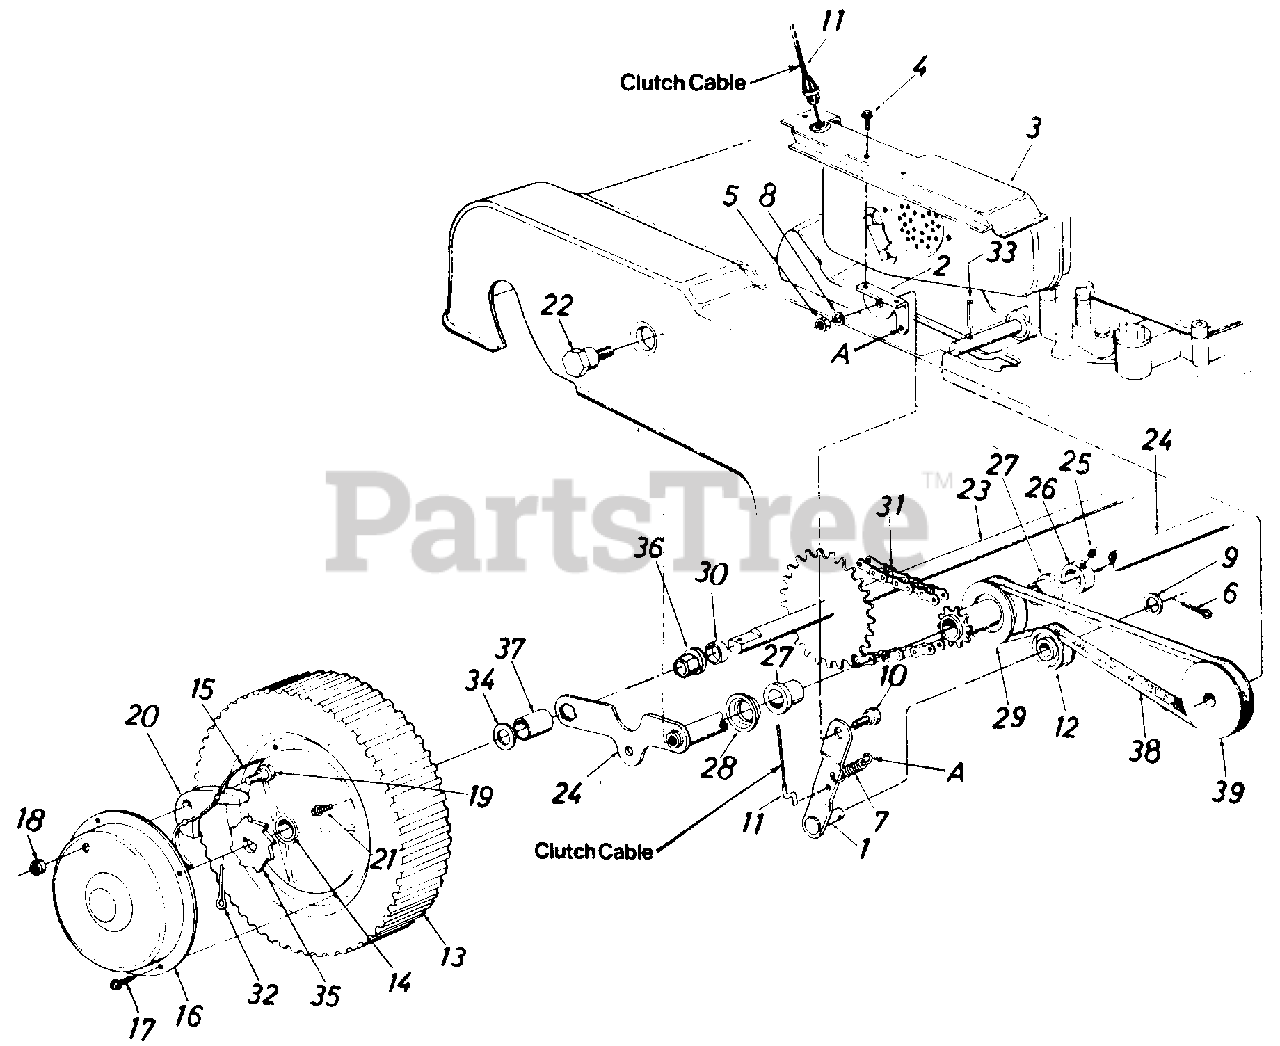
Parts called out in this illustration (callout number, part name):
1	Idler Brkt. Ass'y.
2	Idler Mounting Brkt.
3	Belt Guard
4	Hex Wash. Hd. AB-Tap Scr. 1/4" x .62" Lg.
5	Hex Nut 5/16-18 Thd.
6	Cotter Pin 1/8" Dia. x 1.00" Lg.
7	Extension Spring .33" O.D. x 1.12" Lg.
8	L-Wash. 5/16" I.D.
9	Fl-Wash. .531" I.D. x .930" O.D. x .050
10	Shld. Bolt .375" Dia. x 1.89
11	Clutch Cable - 59"
12	Flat Idler 1.62" Dia.
13	Wheel Ass'y. Comp. (Rear)
14	Flange Brg. 1/2" I.D. (Rear)
15	Spring - Nylon
16	Rear Hub Cap
17	Pan Hd. Tap Scr. #12 x .50"
18	Hex Ins. L-Nut 1/4-20 Thd.
19	Shld. Bolt .342" Dia. x .268
20	Pawl
21	Hex Wash. Hd. Tap Scr. #8 x .50" Lg.
22	Shld. Bolt .625" Dia. x .425"
23	Rear Shaft Ass'y.
24	Rear Axle Ass'y.
25	Set Scr. 5/16-18 x .25" Lg. Cup Point
26	Collar 5/8" I.D.
27	Flange Brg. .634" I.D. Plastic
29	Pulley w/9 Tooth Sprocket Ass'y.
30	Spacer .53" I.D. x .75" O.D. x .38" Lg.
31	#48 Chain 1/2" Pitch x 32 Links
32	Cotter Pin 1/8" Dia. x 1.00"
33	Spring Pin Spir. 3/16" Dia. x 1.50" Lg.
34	Fl-Wash. .531" I.D. x .930" O.D. x .050
35	Ratchet - Rear Wheel
36	Hex Flange Brg. .506" I.D.
37	Spacer .756" I.D. x .89" O.D. x .960" Lg.
38	"V"-Belt 1/2" x 24" Lg.
39	1/2" "V"-Pulley .50" I.D. x 2.52" O.D.
